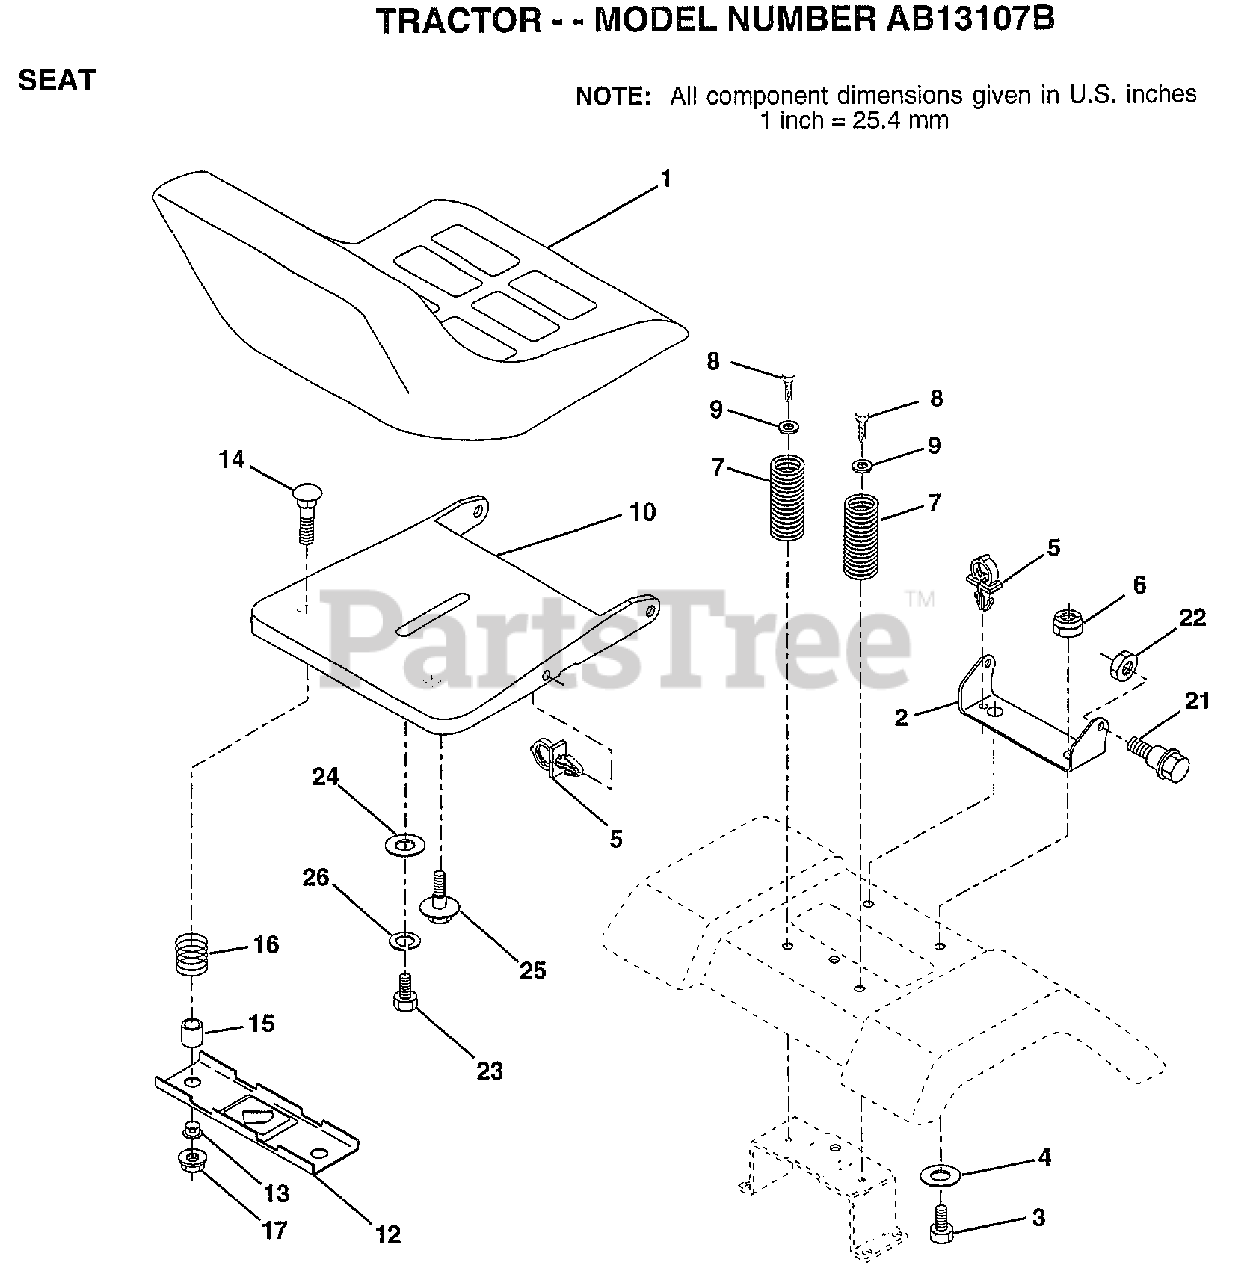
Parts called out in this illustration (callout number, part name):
2	BRACKET PVT SEAT
3	BOLT
4	WASHER PM
5	CLIP.PUSH-IN.HING
6	NUT
7	SPRING COMPRESSIO
8	SCREW GTV
9	WASHER
10	PAN-SEAT
12	BRKT SWITCH
13	BUSHING
14	BOLT-RD HD SQ NK
15	SPLIT SPACER
16	SPRING
21	"BOLT,SHOULDER"
22	NUT
23	BOLT
24	WASHER
25	"BOLT,SHOULDER"
26	LOCKWASHER
